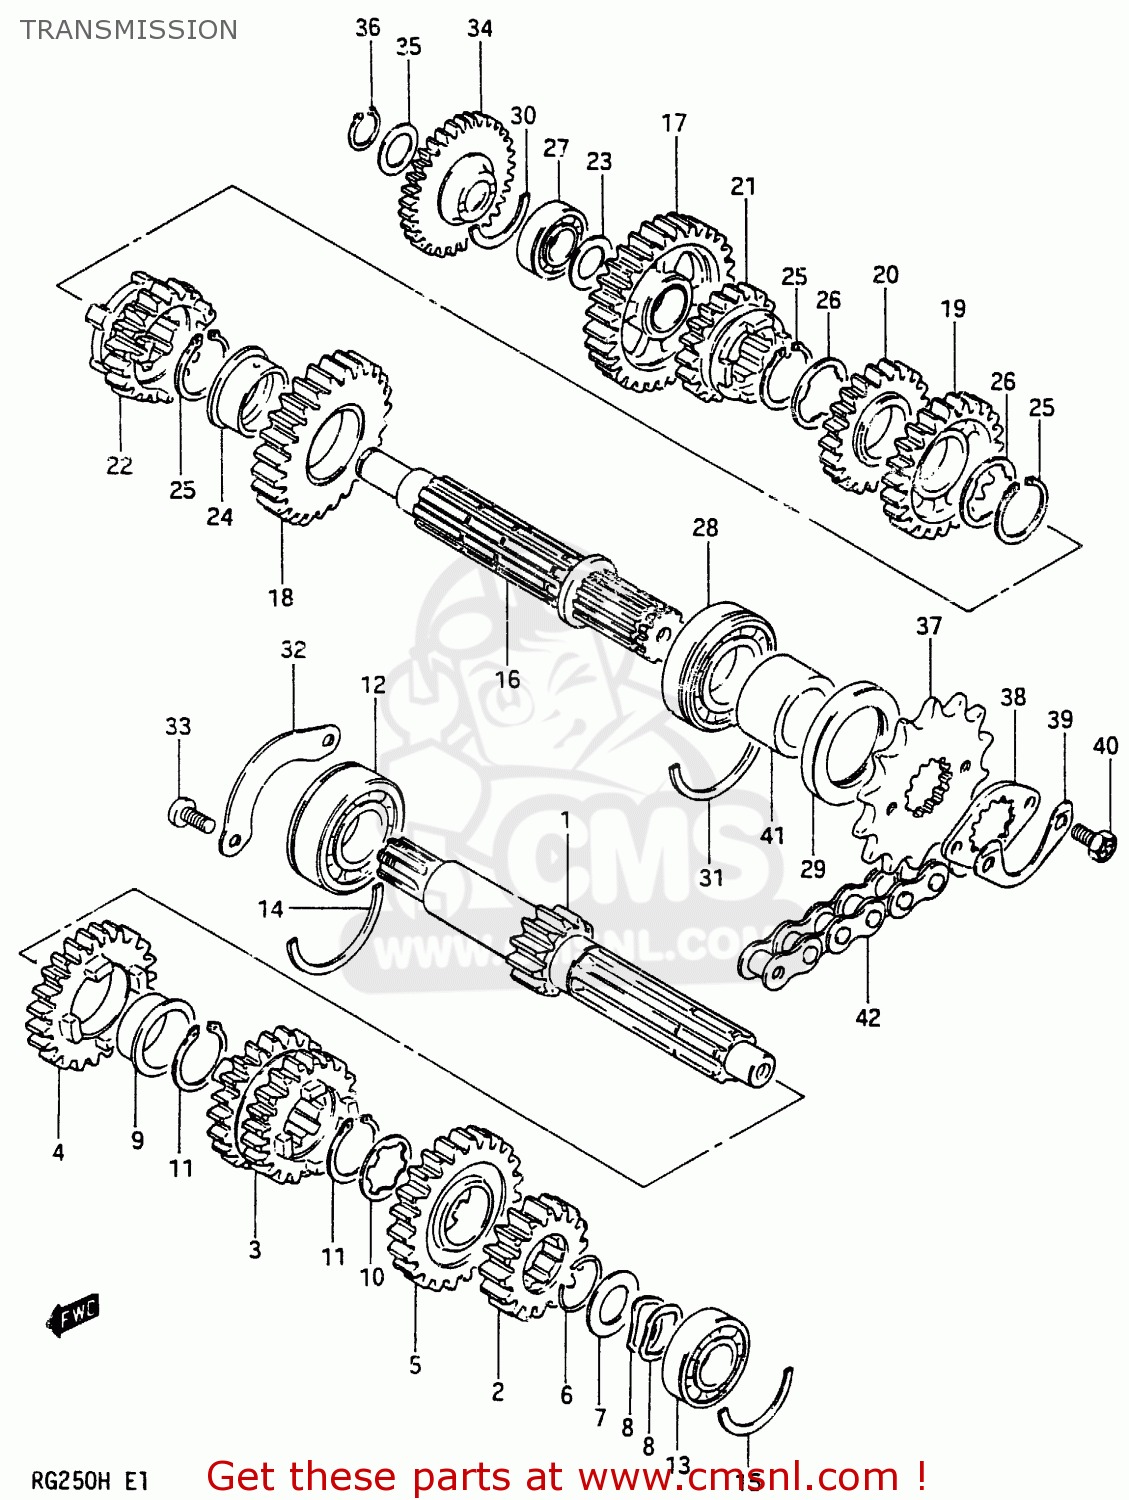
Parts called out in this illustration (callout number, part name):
1	COUNTERSHAFT (NT:13)
2	GEAR, 2ND DRIVE (NT:16)
3	GEAR, 3/4 DRIVE (NT:19/21)
4	GEAR, 5TH DRIVE (NT:22)
5	GEAR, 6TH DRIVE (NT:23)
6	CIRCLIP
7	WASHER (15X26X1.5)
8	WASHER
9	BUSH
10	WASHER,LOCK
11	CIRCLIP
12	BEARING, RH
13	BALL BEARING
14	C RING
15	C RING
16	SHAFT, DRIVE
17	GEAR, 1ST DRIVEN (NT:29)
18	GEAR, 2ND DRIVEN (NT:25)
19	GEAR, 3RD DRIVEN (NT:23)
20	GEAR, 4TH DRIVEN (NT:21)
21	GEAR, 5TH DRIVEN (NT:19)
22	GEAR,6TH DRIVEN(NT:18)
23	WASHER,THRUST
24	BUSH
25	RING,SNAP
26	WASHER,LOCK
27	BALL BEARING
28	BEARING
29	SEAL,OIL(34X52X6)
30	C RING
31	C RING
32	RETAINER, BEARING
33	SCREW 6X12
34	GEAR, KICK STARTER (NT:33)
35	WASHER,THRUST
36	CIRCLIP,15MM
37	SPROCKET,ENGINE(NT:14)
38	PLATE,SPROCKET
39	LOCK WASHER,SPROCKET
40	BOLT
41	SPACER (25X34X14.3)
42	CHAIN, DRIVE (DID 520VX110LE)
